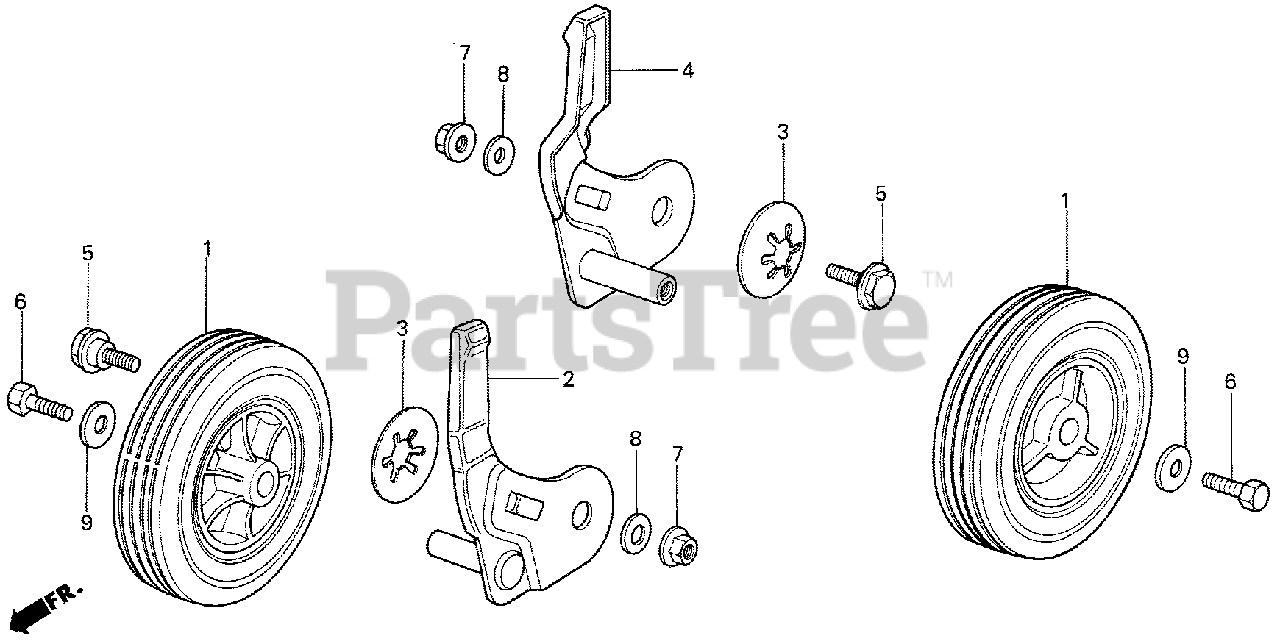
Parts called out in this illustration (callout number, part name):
1	WHEEL, FR. (6 INCH)
2	ARM, R. FR. ADJUSTING (NOT AVAILABLE)
3	SPRING, ADJUSTING ARM
4	ARM, L. FR. ADJUSTING (NOT AVAILABLE)
5	SHAFT, ADJUSTING CENTER (NOT AVAILABLE)
6	BOLT, HEX. (8X12)
7	NUT, FLANGE (8MM)
8	WASHER, PLAIN (8MM)
9	WASHER, PLAIN (8MM)
